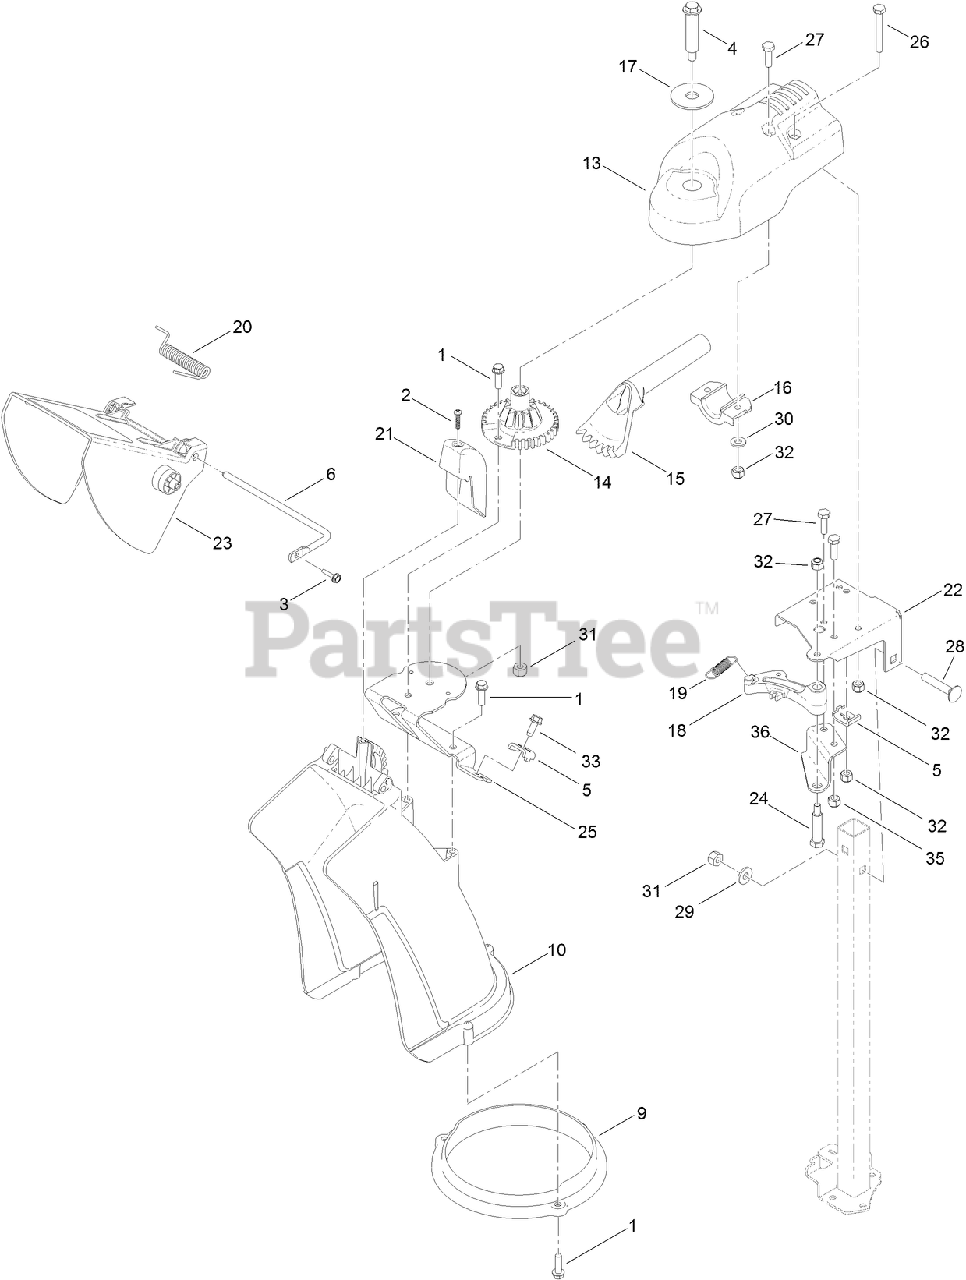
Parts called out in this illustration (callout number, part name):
1	SCREW-HWH
2	SCREW-PPH
3	SCREW-HWH
4	BOLT-SHOULDER
5	CLAMP-CABLE
6	ROD-DEFLECTOR
9	RING-CHUTE
13	MOUNT-CHUTE, DISCHARGE
14	GEAR-CHUTE
15	GEAR-BEVEL
16	MOUNT-GEAR, BEVEL
17	WASHER-FLAT
18	LATCH-CHUTE
19	SPRING-LATCH, CHUTE
20	SPRING-TORSION
21	CHUTE-COVER
22	BRACKET-SUPPORT, CHUTE
23	DEFLECTOR-CHUTE
24	BOLT-SHOULDER
25	BRACKET-MOUNT, CHUTE
26	SCREW-HH
27	SCREW-HH
28	BOLT-CAR
29	WASHER-FLAT
30	WASHER-FLAT
31	NUT-LOCK, NI
32	NUT-LOCK, NI
33	SCREW-HWH
35	NUT-LOCK, NI
36	BRACKET-SUPPORT, LATCH
